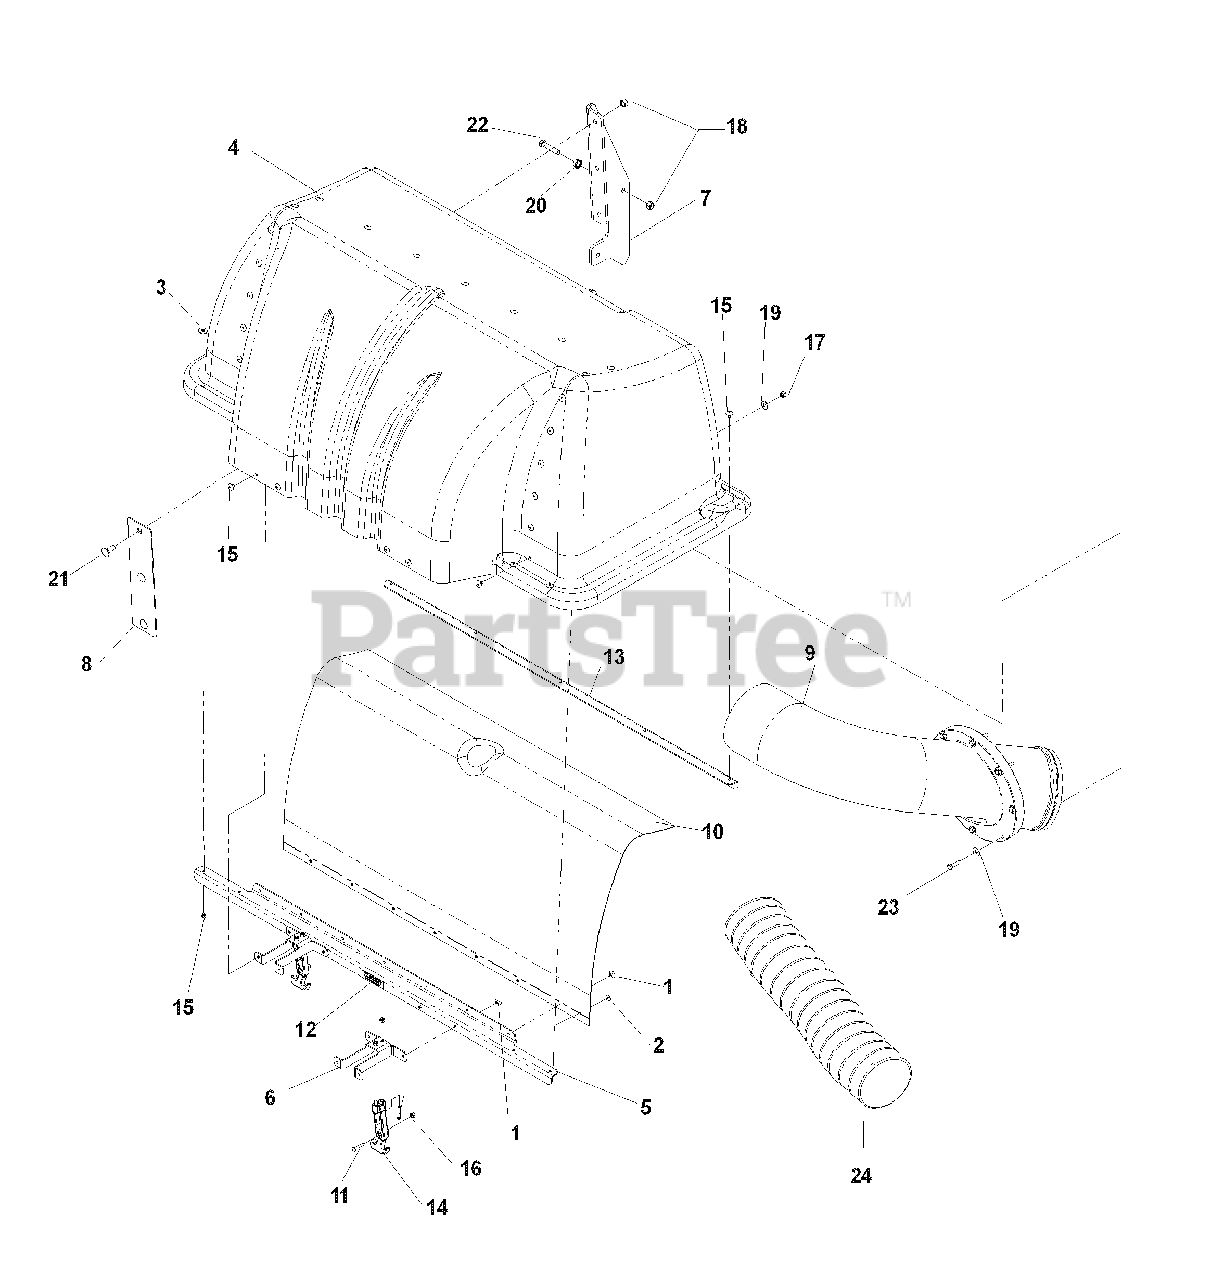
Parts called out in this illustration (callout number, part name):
1	RIVET, 3/16 x 1/4
2	WASHER, #10
3	WASHER, #10, MACH
5	HOOD SUPPORT
6	SUPPORT, DRAW LATCH
7	HOOD HINGE
8	MOUNT PLATE
9	INLET TUBE
10	MESH, POLY DIAMOND
11	SCREW, #10-24 x 1 1/8
12	DECAL, VENTILATION
13	HOOD SUPPORT, REAR
14	DRAW LATCH, T-HANDLE
15	RIVET, 3/16
16	NUT, #10-24, NYLOC
17	NUT, 1/4 -20, NYLOC
18	NUT, 3/8 -16, NYLOC
19	WASHER, 1/4
20	NUT, 3/8 -16, WHIZLK
21	RHSNB, 3/8-16 x 1
22	HCS, 3/8-16 x 1 3/4
23	HCS, 1/4-20 x 1 3/4
